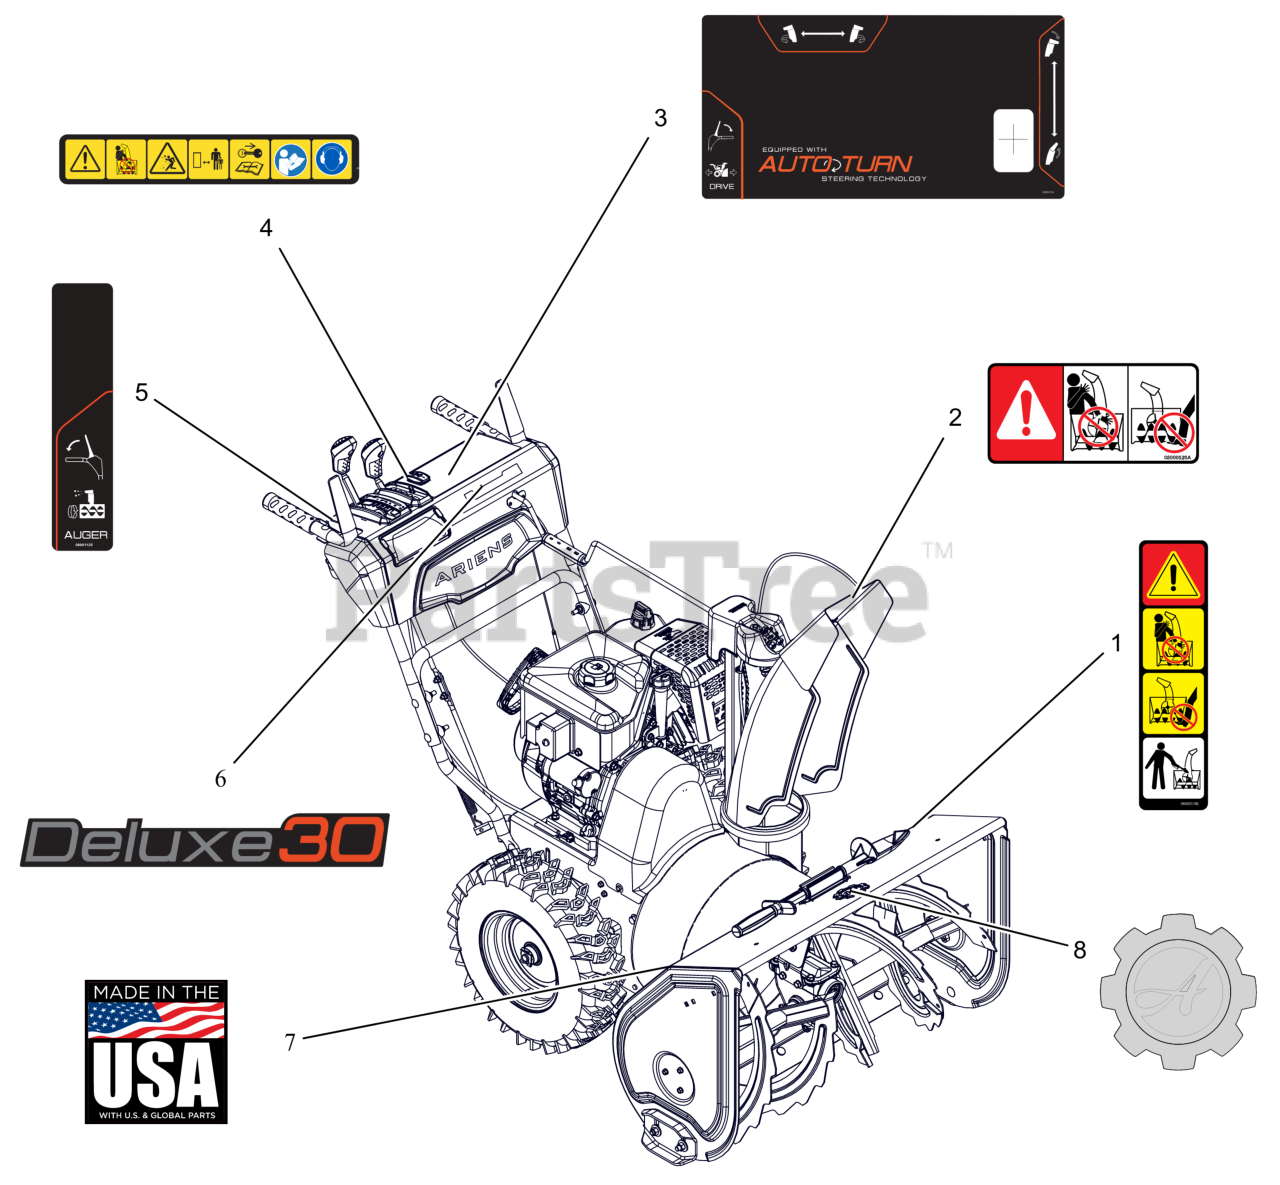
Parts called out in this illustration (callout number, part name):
1	DECAL, DANGER - ROTATING PARTS
2	DECAL, DANGER
3	DECAL,CONTROL-LG ID
4	DECAL,DASH - SAFETY
5	DECAL,CONTROL-RH CONTROL
6	DECAL, DASH - DELUXE 30
7	DECAL, MADE IN USA
8	DECAL, ARIENS-GEAR BADGE -THK
